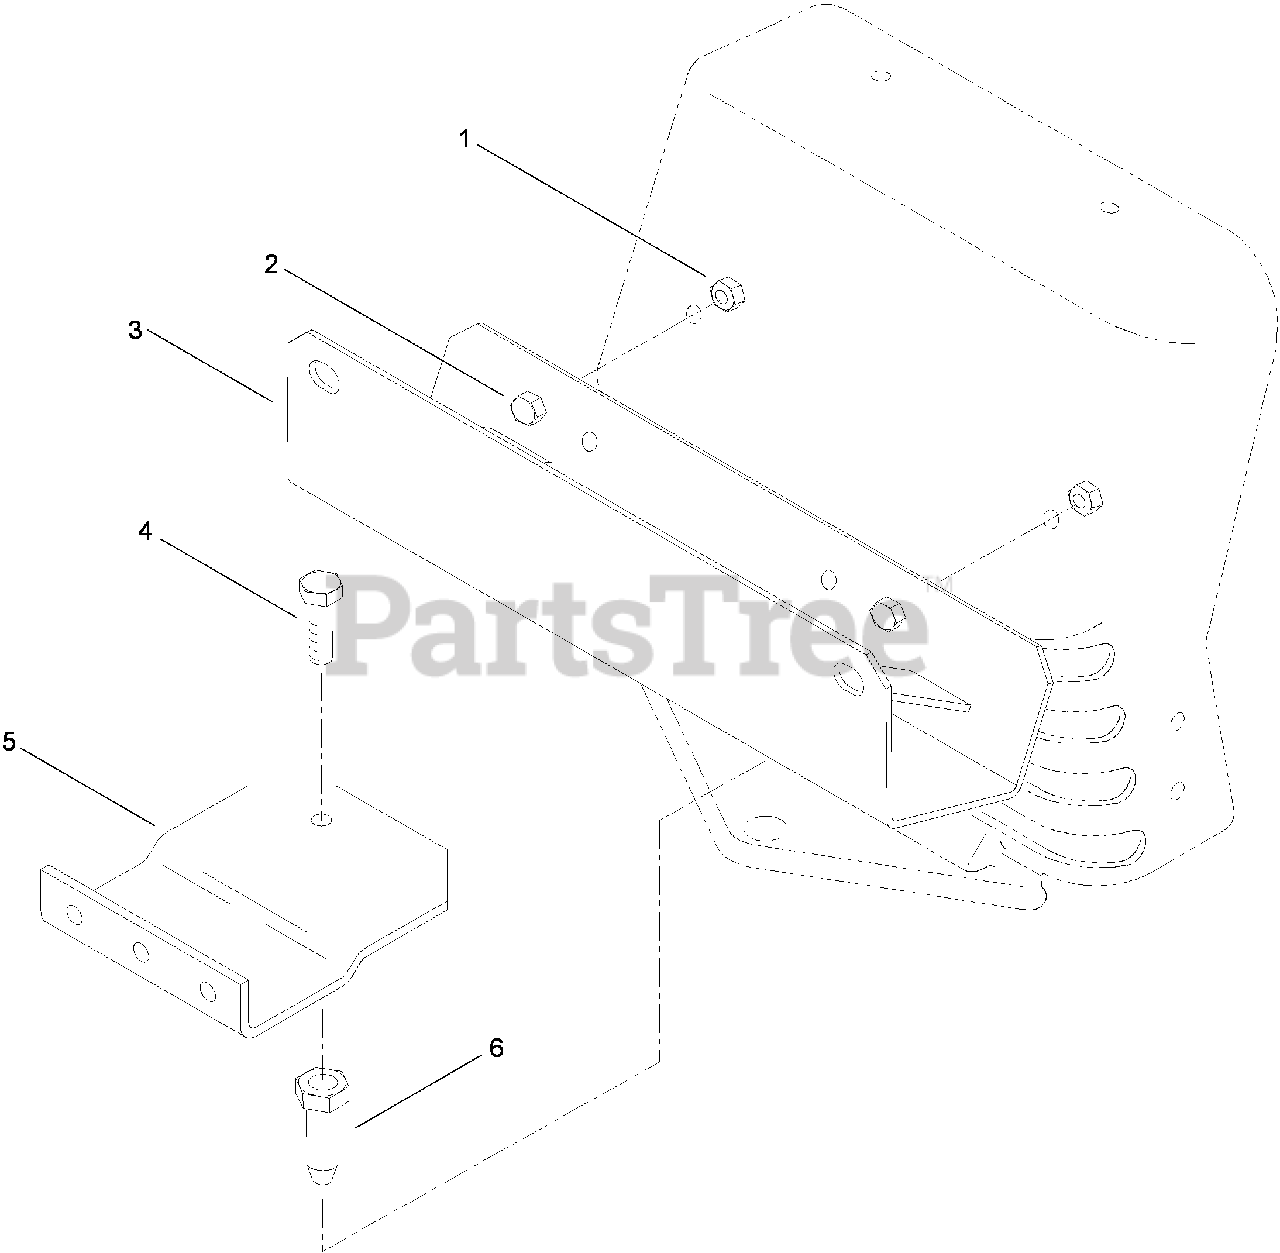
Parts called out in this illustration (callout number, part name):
1	NUT-LOCK, NI
2	SCREW-HH
3	BRACKET-CHANNEL
4	SCREW-HH
5	BRACKET-BAG MOUNT
6	PIN-MOUNTING, LOWER
